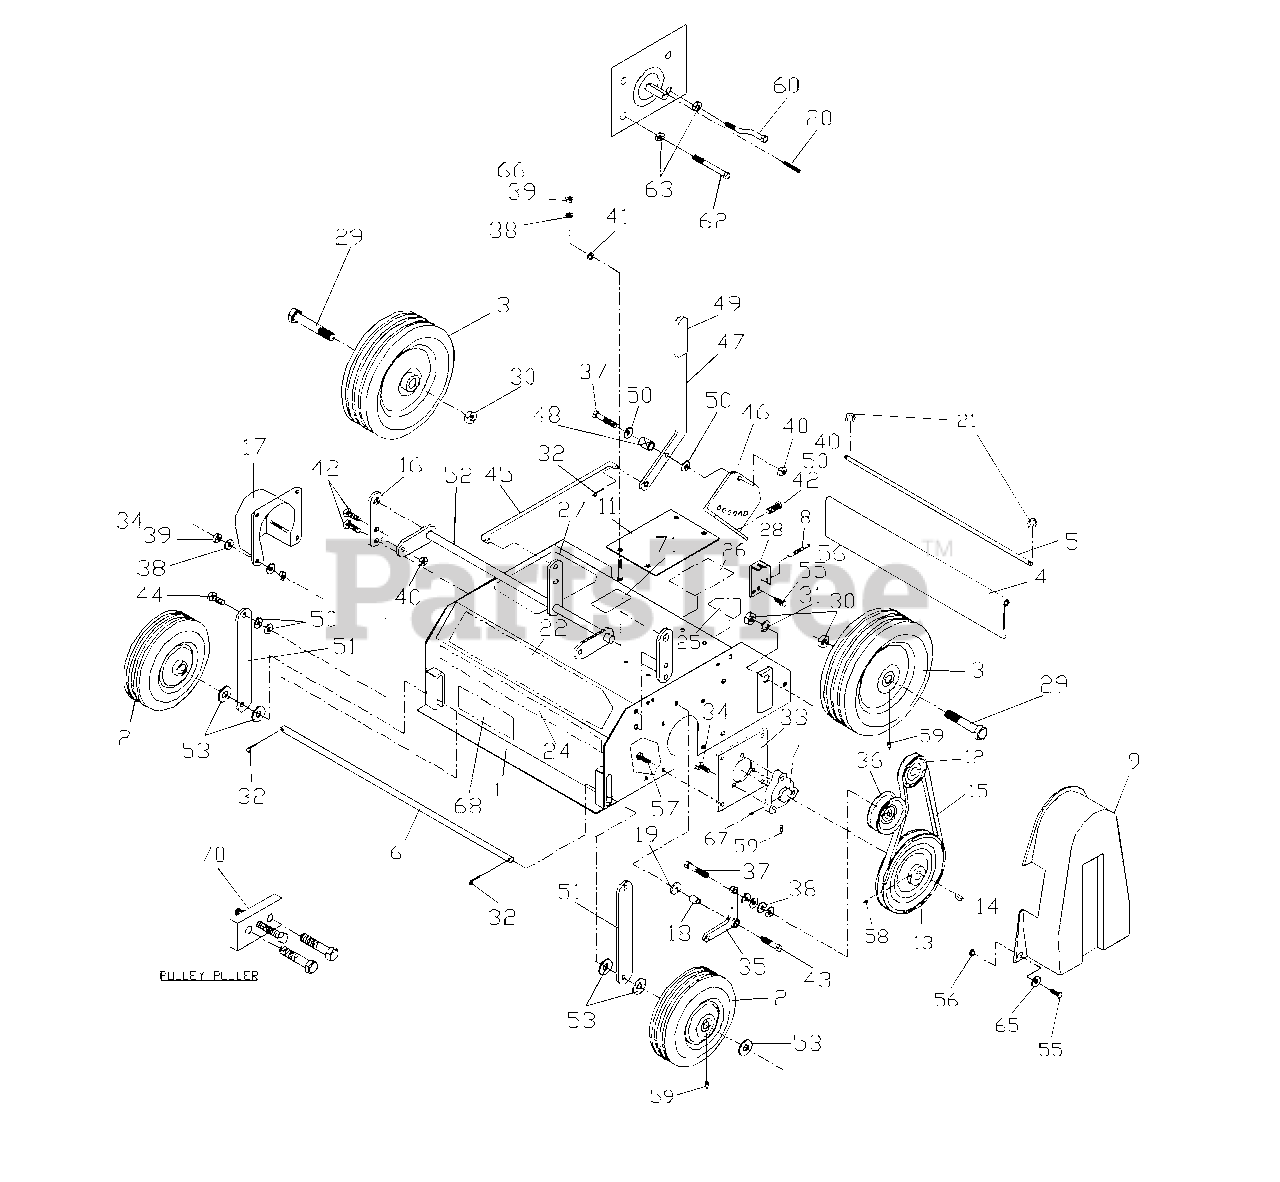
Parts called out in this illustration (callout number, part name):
1	DETHATCHER BODY W/DECALS
1	SLICER BODY W/DECALS
2	FRONT WHEEL
3	REAR WHEEL
4	DEFLECTOR SHIELD
5	DEFLECTOR ROD
6	FRONT AXLE
7	FLANGED BEARING
8	EXTENSION SPRING
9	BELT GUARD
11	ENGINE PAD
12	ENGINE DRIVE PULLEY
13	MAIN SHAFT PULLEY
14	#9 WOODRUFF KEY
15	DRIVE BELT
17	SHAFT GUARD
18	OILITE BEARING
20	3/16 X 1-3/4 SQUARE KEY
21	5/16 RETAINING RING
22	DECAL, HUSQVARNA
24	DECAL, DT20
25	DECAL, WARNING SM.
26	DECAL, WARNING LG.
27	DECAL, ADJUSTING
28	CABLE BRACKET
29	5/8 X 4 AXLE BOLT
30	5/8-11 HEX JAM NUT
31	5/8 LOCK WASHER
32	1/8 X 3/4 COTTER PIN
34	5/16-18 X 1-1/4 TAP BOLT
35	BELL CRANK
36	IDLER PULLEY
37	3/8-16 X 2 HCS
38	5/16 FLAT WASHER
39	5/16-18 NYLOC NUT
40	3/8-16 NYLOC NUT
41	5/16 LOCK WASHER
42	3/8-16 X 1 HCS
43	3/8-16 X 1-1/2 HCS
44	3/8-16 X 1-1/2 HCS
45	LINKAGE ARM
46	ADJUSTMENT GAUGE
47	ADJUSTING LEVER
48	COMPRESSION SPRING
49	LEVER GRIP
50	3/8 FLAT WASHER
52	HEIGHT ADJUSTING ROD
53	1/2 FLAT WASHER
55	1/4-20 X 5/8 HCS
56	1/4-20 NYLOC NUT
57	5/16-18 X 3/4 HCS
58	5/16-18 X 3/8 SET SCREW
59	1/4-28 STR. ZERK
60	BELT GUIDE, OFFSET
62	5/16-24 X 2-3/4 HCS
63	5/16-24 HEX JAM NUT
65	1/4 FLAT WASHER
66	5/16-18 X 1-3/4 HCS
67	#10-32 X 1/4 SET SCREW
68	DECAL, NASCAR
70	PULLEY PULLER
71	DECAL, WARNING
